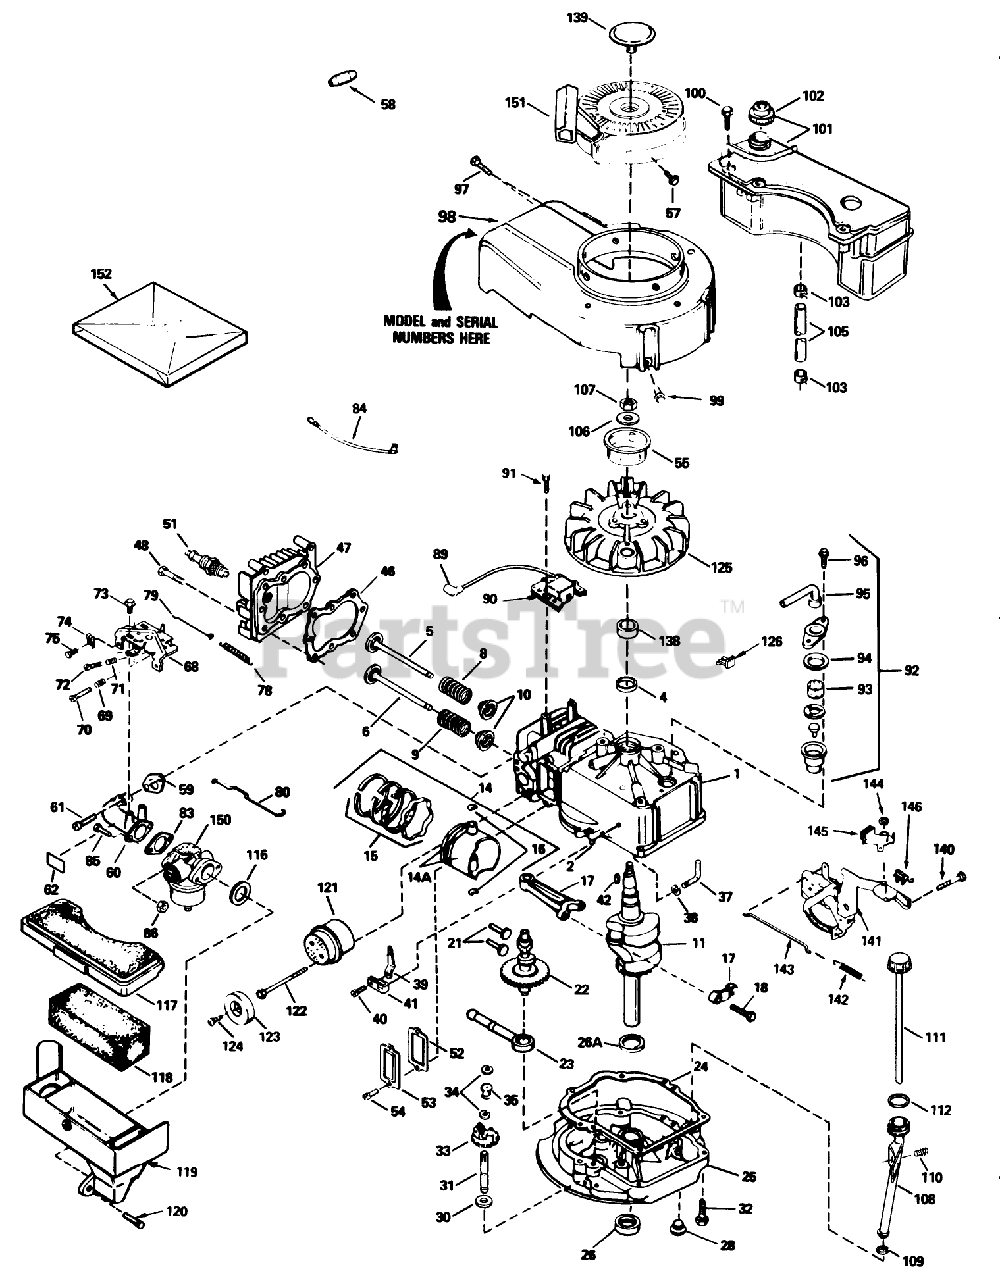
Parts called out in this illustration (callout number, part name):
1	Cylinder Assy. (Incl. #24)
2	Pin-Dowel
4	Seal-Oil
5	Valve, Intake (Std.) (Incl. Ref. #40)
5	Valve, Intake (1/32" oversize)(Incl. No. 40)
6	Valve, Exhaust (Std.)(Incl. No. 40)
6	Valve, Intake (1/32" oversize)(Incl. No. 40)
8	Seal Assy., Intake
9	Spring-Valve
10	Cap-Valve, Spring
11	Crankshaft
14	Piston-Pin Ring Assy. (Std.)(Incl. Ref. #16A, 17 18)
14	Piston-Pin Ring Assembly (.010 oversize)(Incl. Ref. #16A, 17 18)
14	Piston, Pin Ring Assy. (.020 Oversize)(Incl. Ref. #13A, 14, 15)
14A	Piston Pin Assy. (Std.)(Incl. Ref. #14)
14A	Ass-y Spindle R H
14A	Piston Pin Assy. (.020 Oversize) (Incl. Ref. #14)
15	Ring Set-Piston (Std.)
15	Ring Set, Piston(.0100versize)
15	Ring Set (.020" OS)
16	Ring-Retaining, Piston Pin
17	Rod Assy., Connecting (Incl. Ref. #17)
18	OA Bolt-Connecting Rod
21	Lifter-Valve
22	Camshaft(Mech.Comp. Release)
23	Oil Pump ASM
24	*35261 Gasket-Mounting Flange
25	Flange-Mounting (Incl. Ref. #26, 27 39)
26	Seal-Oil
26A	Washer-Thrust
28	Plug Oil Drain
30	Washer-Flat
31	Shaft-Governor
32	Screw (1/4-20 x 1-1/4)
33	Governor Gear ASM
34	Ring-Retaining
35	Spool-Governor
37	Rod, Governor (Incl. No. 36)
38	Washer-Flat
39	Governor Lever
40	Screw
41	Clamp-Lever, Governor
42	Key-Flywheel
46	63573 GIL 42 SNWTHW
47	Head-Cylinder
48	Screw (5/16-18x1-1/2)
51	Spark Plug-Resistor (R J19 L M)
52	Gasket-Breather
53	Cover-Valve
54	Screw
55	Hub-Starter
57	Screw, Hex Hd.
58	Retainer-Starter Rope
59	Gasket-Intake
60	Pipe-Intake (Incl. Ref. #59)
61	Screw (1/4-20 x 1)
62	Decal-Primer
68	Control Assy.-Remote Speed (Incl. Ref. #69 thru 72 76)
69	61709/GIL1515A/95-5
70	Screw
71	Spring-Compression
72	Screw
73	Screw (10-24 x 9/16)
74	Conduit
75	Screw (10-32 x 3/8)
78	Spring Governor
79	2035A67 ADD.ASSEMBL
80	Link-Throttle
83	Gasket
84	Ground Wire
86	Nut and Lock Washer (1/4-28)
89	Cover-Spark Plug
90	Solid State
91	Screw
92	Breather Assy. (Incl. Ref. #46 thru 51)
93	Element-Breather
94	Gasket-Breather
95	Tube, Breaker
96	Screw (10-24 x 9/16)
97	Screw (10-24 x 9/16)
98	Housing-Blower
99	Screw (1/4-20 x 1/2)
100	Screw (10-32 x 35/64)
101	Tank Assembly-Fuel (Incl. Ref. #102)
102	Cap-Fuel
103	Clamp-Line, Fuel
105	Line-Fuel
106	Washer-Belleville
107	Nut-Flywheel
108	Oil Fill Tube
109	Gasket
110	Screw (10-32 x 1/2)
111	Dipstick
112	O-Ring
116	Gasket-Cleaner, Air
117	Cover Air Cleaner
118	Filter-Air Cleaner
119	Body Air cleaner
120	Screw
121	B Muffler (Incl. Ref. #122)
122	Screw
123	Cover-Muffler
124	Screw (8-32 x 3/8)
125	Flywheel
126	Clip-Wire
138	Spacer
139	Plug Starter
140	Screw (1/4-20 x 3/8)
141	Bracket-S.E. Brake
142	Spring-Extension
143	Link-Control
144	Ring-Retaining
145	Lever-Brake
146	Terminal
150	Carburetor (Incl. Ref. #83)
151	Starter-Rewind
152	Gasket Set
